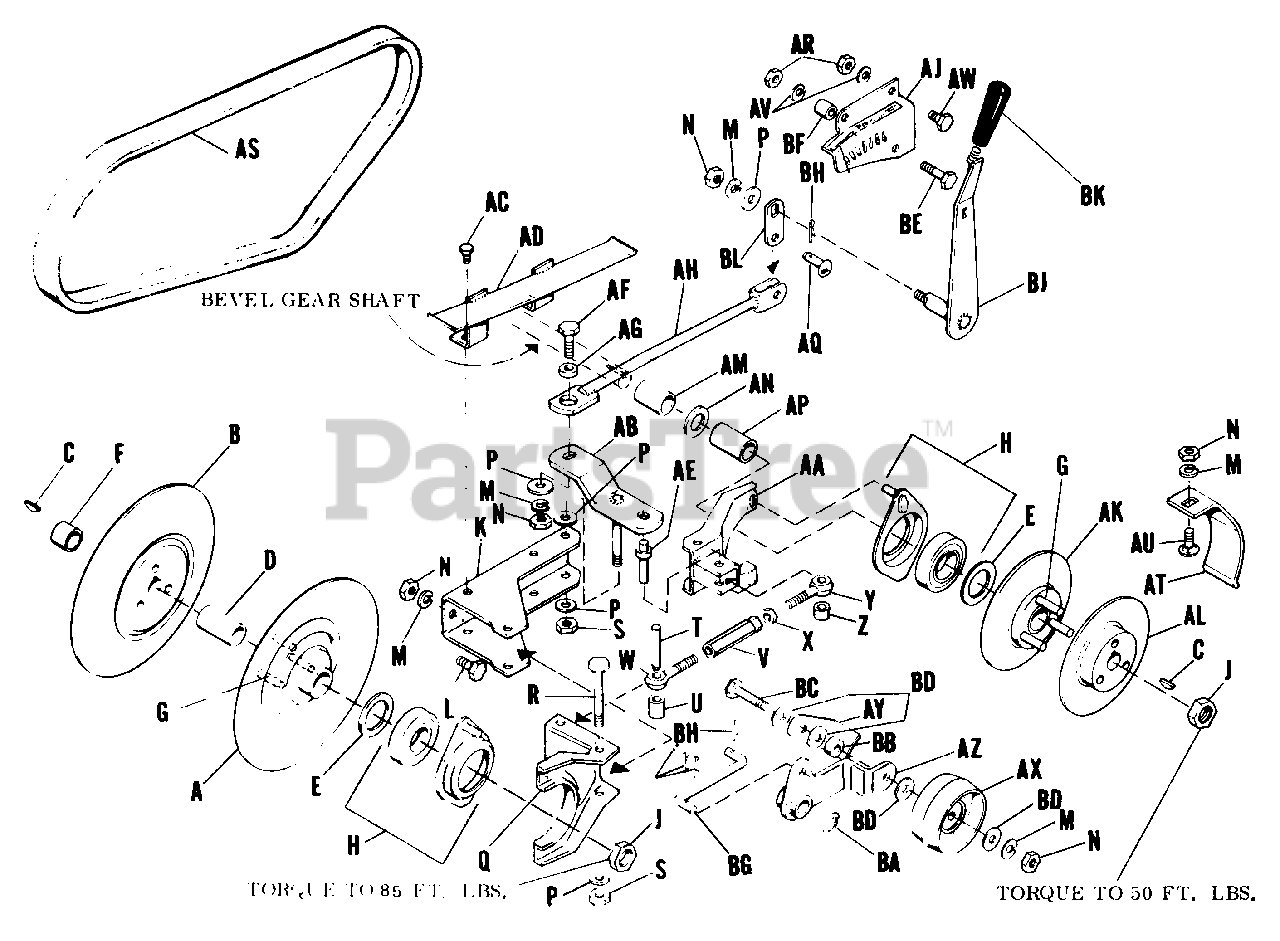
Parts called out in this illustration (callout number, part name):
A	Pulley-Half Assembly
B	Pulley-Half
D	Driver Slide Spacer Teflon Coated
H	Retainer Ring/Bearing Assembly
J	Hex Jam Nut, Lock
K	Variable Speed Bracket
L	Hex Capscrew, 3/8"-16 x 7/8" lg.
M	Lock Washer, 3/8"
N	Hex. Nut, 3/8"-16
P	Plain Washer, 3/8"
Q	Transmission Fork Assembly
R	Special Screw
S	Hex Nut, 3/8"-16 Lock
T	Pivot Pin
V	Turnbuckle Body
W	Eyebolt, R.H.
X	Hex Nut, 3/8"-21
Y	Eyebolt, L.H.
AA	Bevel Gear Housing Fork Assy.
AB	Fork, Rocker Assy.
AC	Screw, Taptite, 1/4"-20 x 5/8" lg.
AD	Belt Guard Assembly
AF	Hex Capscrew, 3/8"-16 x 1-1/4" lg.
AH	Arm Assembly
AK	Pulley-Half Assembly
AL	Pulley-Half
AM	Slide Spacer
AN	Stop Washer
AP	Slide Spacer (Teflon Coated)
AR	Hex Nut, 5/16"-18
AS	BELT, HI, 54"
AT	Belt Guard
AU	Carriage Bolt, 3/8"-16 x 5/8" lg.
AV	Lock Washer, 5/16"
AW	Hex Capscrew, 5/16"-18 x 5/8" lg.
AX	Idler Pulley
AY	Idler Belt Stop
AZ	Idler Lever Assembly
BA	Retaining Ring
BC	Hex Capscrew, 3/8"-16 x 2" lg.
BD	Plain washer, 5/16"
BE	Hex Capscrew, 5/16"-18 x 1-1/2" lg.
BG	Clutch Link
BH	Cotter Pin
BJ	Lever Assembly
BM	Film Quardrant
BN	Film Instruction
